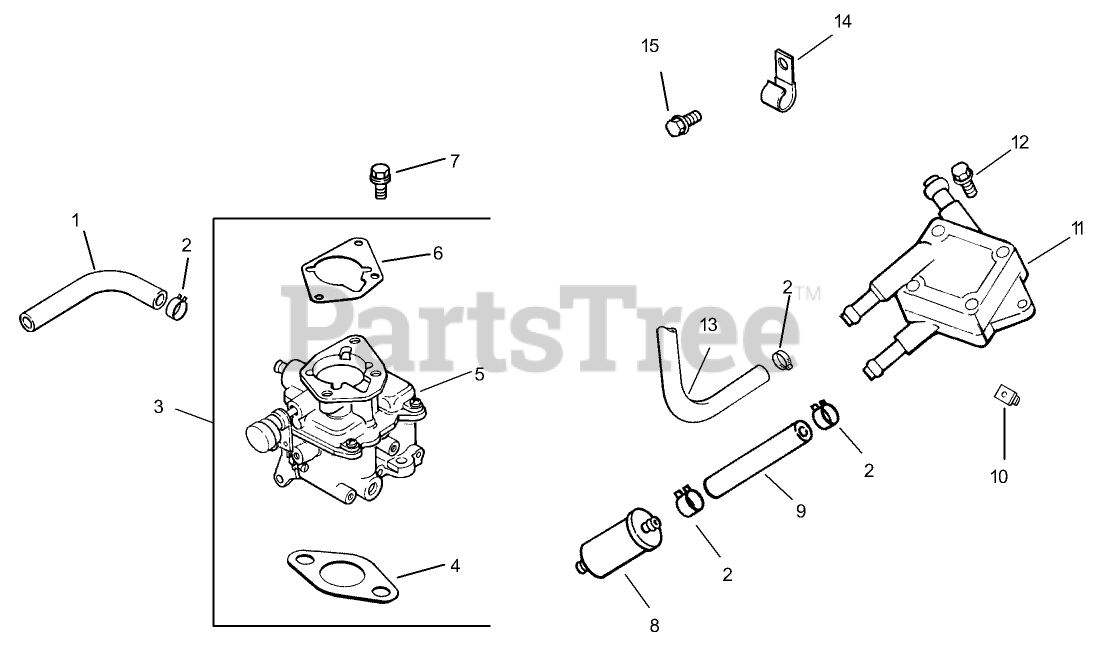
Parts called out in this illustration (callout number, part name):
1	Line-Fuel (9.5)
2	CLAMP-HOSE, SPRING (1/2)
3	Kit, carburetor w/gasket (Includes 4-6)
4	Gasket-Carburetor
5	Carburetor assembly (For information only, not available separately)(Service with kits 24 757 01-S, 24 757 02-S, 24 757 03-S, 24 757 07-S, 24 757 08-S, and 24 757 09-S)
6	GASKET-BASE, AIR CLEANER
7	SCREW-FLANGE (M6X1.0X30)
8	Filter-Fuel
9	Line-Fuel (3.5)
10	Nut-Plastic
11	PUMP-FUEL
12	SCREW-TAP (M6X1.7X18)
13	Line-Fuel, Flexible (15.5)
14	CLIP-CABLE
15	Screw-HF (M6x1.0x12)
